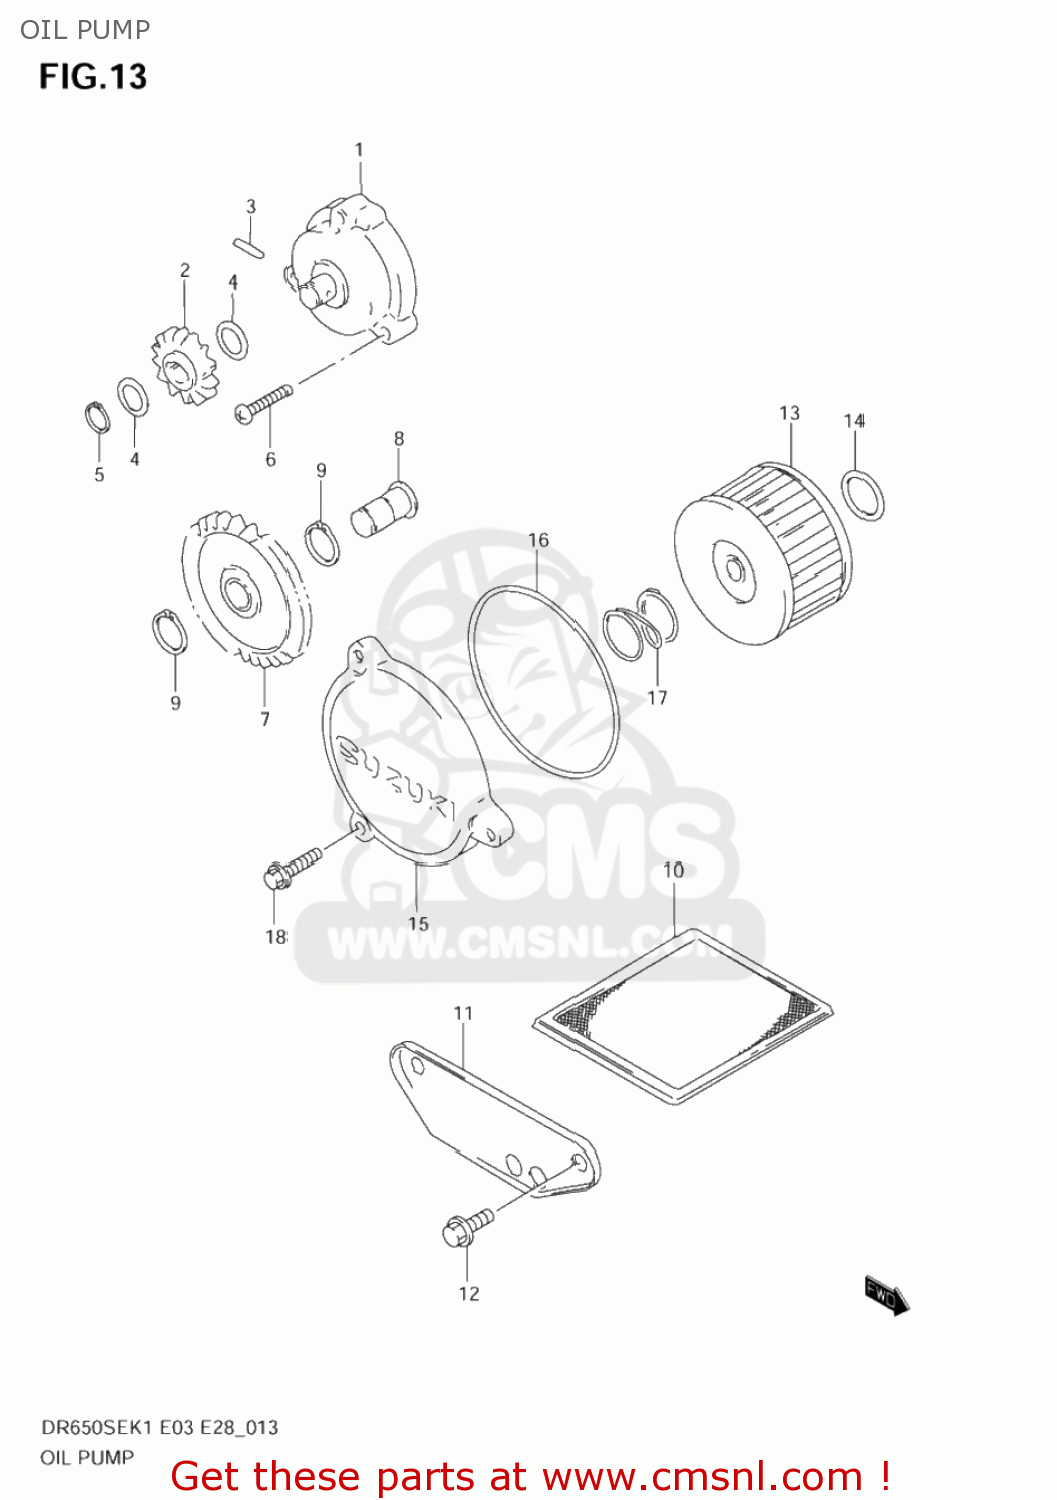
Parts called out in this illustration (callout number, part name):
1	PUMP ASSY,ENGINE OIL
2	GEAR,ENG OIL PUMP DRIVEN
3	PIN(4X15.8)
4	SHIM
5	CIRCLIP,10MM
6	SCREW
7	GEAR,OIL PUMP DRIVE(NT:30)
8	SHAFT,ENGINE OIL PUMP DRIVE
9	CIRCLIP,12 MM
10	STRAINER,ENGINE OIL
11	CAP,OIL STRAINER
12	BOLT 6X12
13	FILTER ASSY,ENGINE OIL
14	O RING(D:2.4,ID:15.8)
15	CAP,OIL FILTER
16	O RING(D:2.4,ID:73)
17	SPRING
18	BOLT
